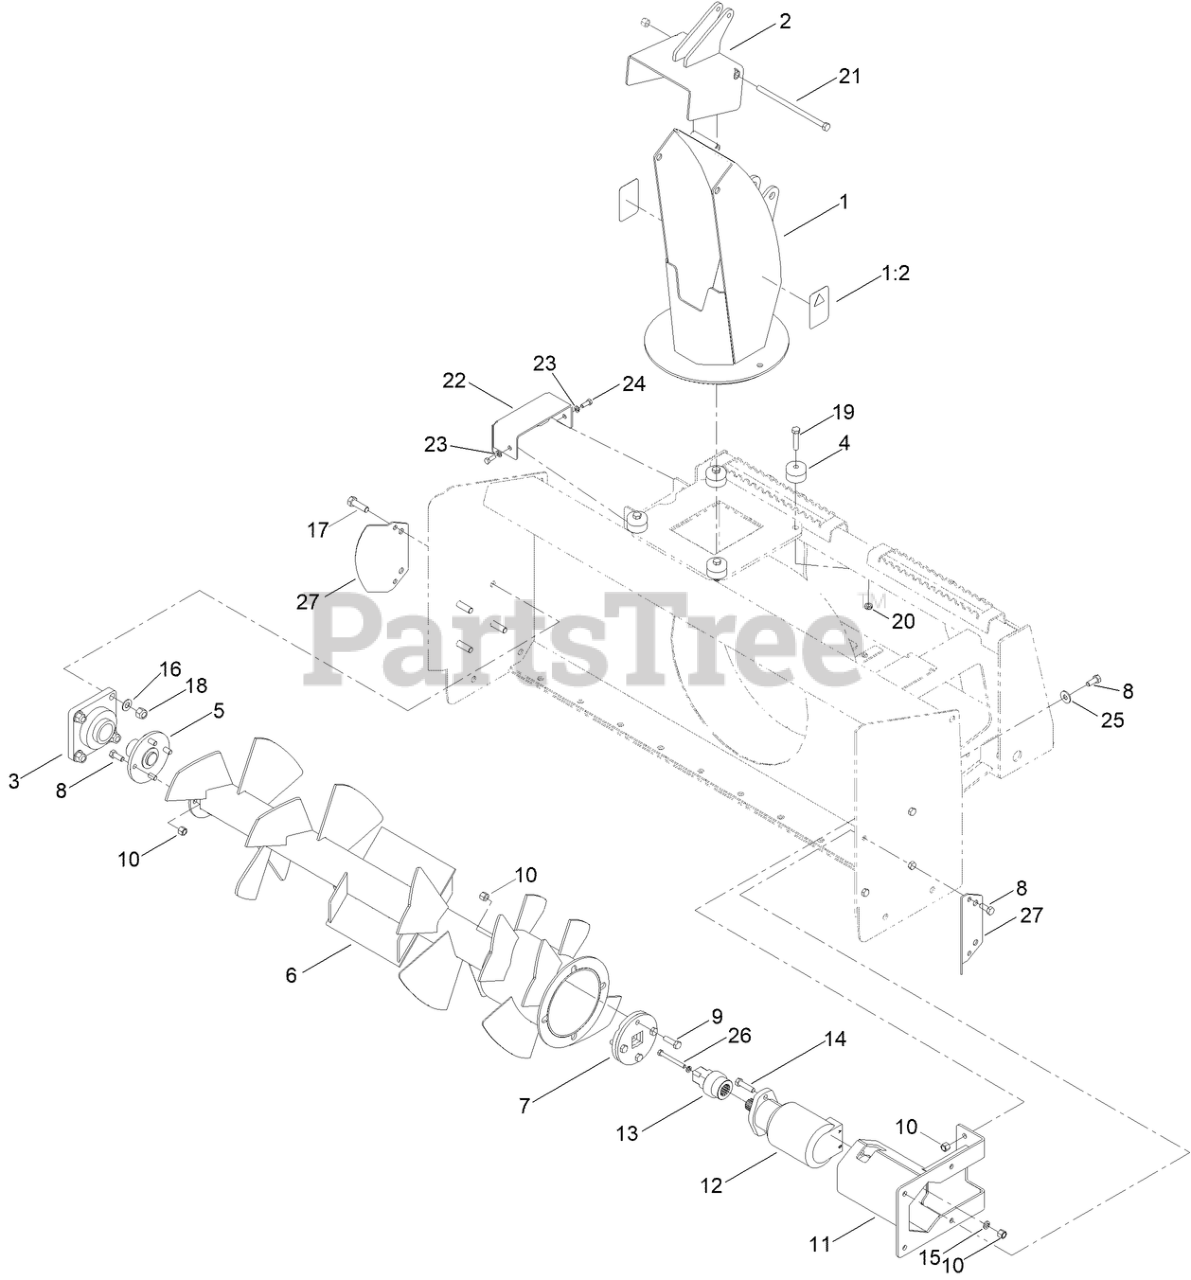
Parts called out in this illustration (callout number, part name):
1	CHUTE-SNOWBLOWER,
1:2	DECAL-DANGER, DISCHARGE
2	DEFLECTOR
3	BEARING-FLANGED
4	RETAINER-SPOUT
5	SHAFT- AUGER FOLLOWER
6	AUGER-SNOW BLOWER
7	FLANGE-DRIVE
8	SCREW-HH
9	SCREW-HH
10	NUT-LOCK, NI
11	MOUNT-AUGER MOTOR
12	MOTOR-HYD. AUGER
13	ADAPTER-MOTOR
14	SCREW-HH
15	WASHER-LOCK
16	WASHER-FLAT
17	SCREW-HH
18	NUT-LOCK, NI
19	SCREW-HH
20	NUT-HEX
21	BOLT-HH
22	GUARD-SNOW BLOWER
23	WASHER-LOCK
24	SCREW-HH
25	WASHER-FLAT
26	SCREW-HH
27	PLATE-SIDE,SNOW
